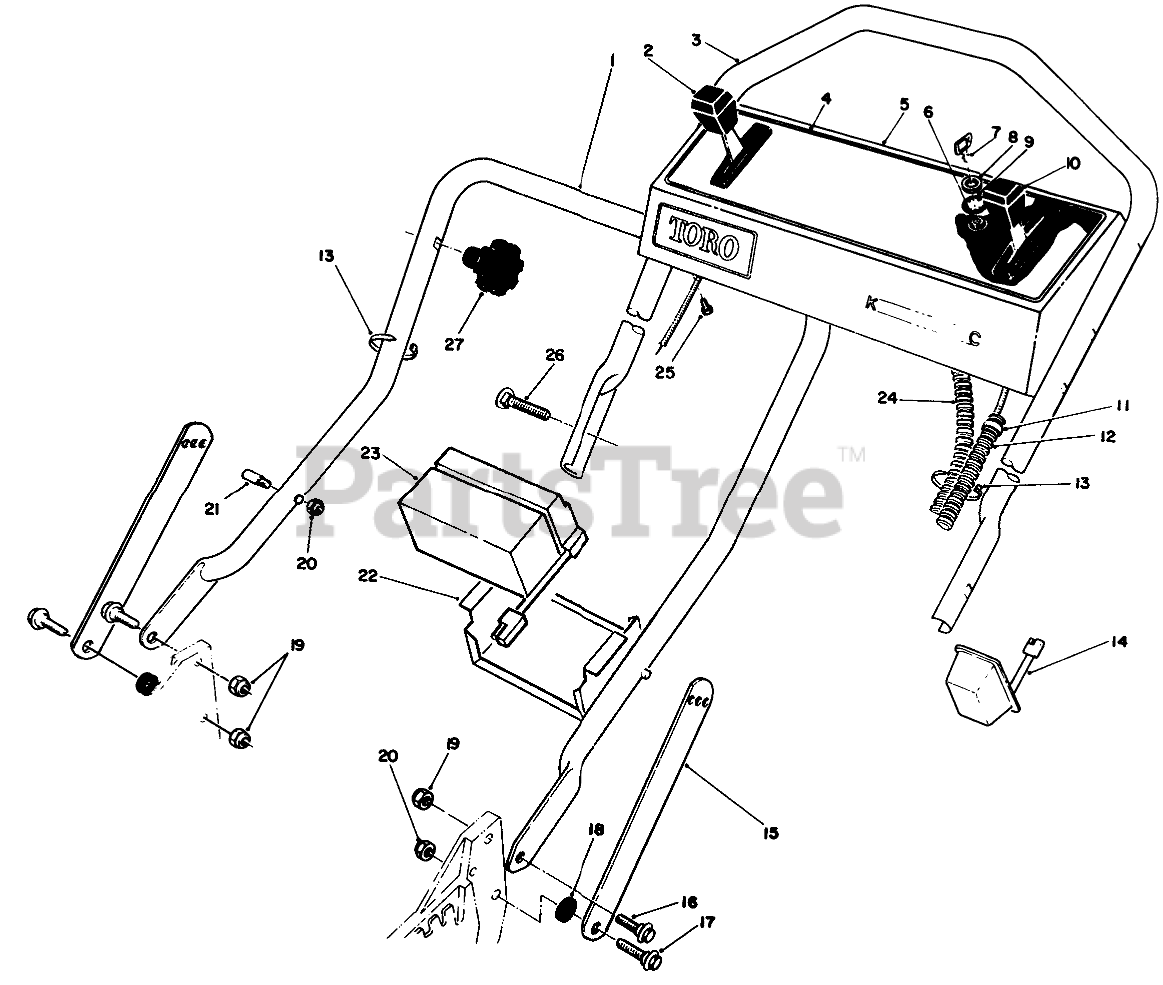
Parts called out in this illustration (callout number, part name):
1	LOWER HANDLE ASM
2	GROUND SPEED CONTROL
3	Handle-Upper
4	Decal-Instruction Panel
5	PANEL W/DECAL
6	Switch-Starter (Incl. Ref. #8-9)
7	KEY-IGNITION
9	WASHER-TOOTH, INTERNAL
10	Control-Throttle (Sheath Lg. 55 1/2 inch, 140.9 cm.)(Wire Lg. 2 1/8 inch, 5.4 cm.)
11	FITTING-RING
12	CONTROL CABLE COVER
13	TIE-CABLE
14	Charger
15	Handle Latch
16	SCREW-SHOULDER
17	SCREW-SHOULDER
18	SPACER
19	NUT-LOCK, NI
20	NUT-LOCK, NI
21	HANDLE PIN
22	BATTERY RETAINER
23	Battery
24	WIRE HARNESS
25	SCREW-HWHTF
26	5/16-18 X 2 HNDLE SCREW
